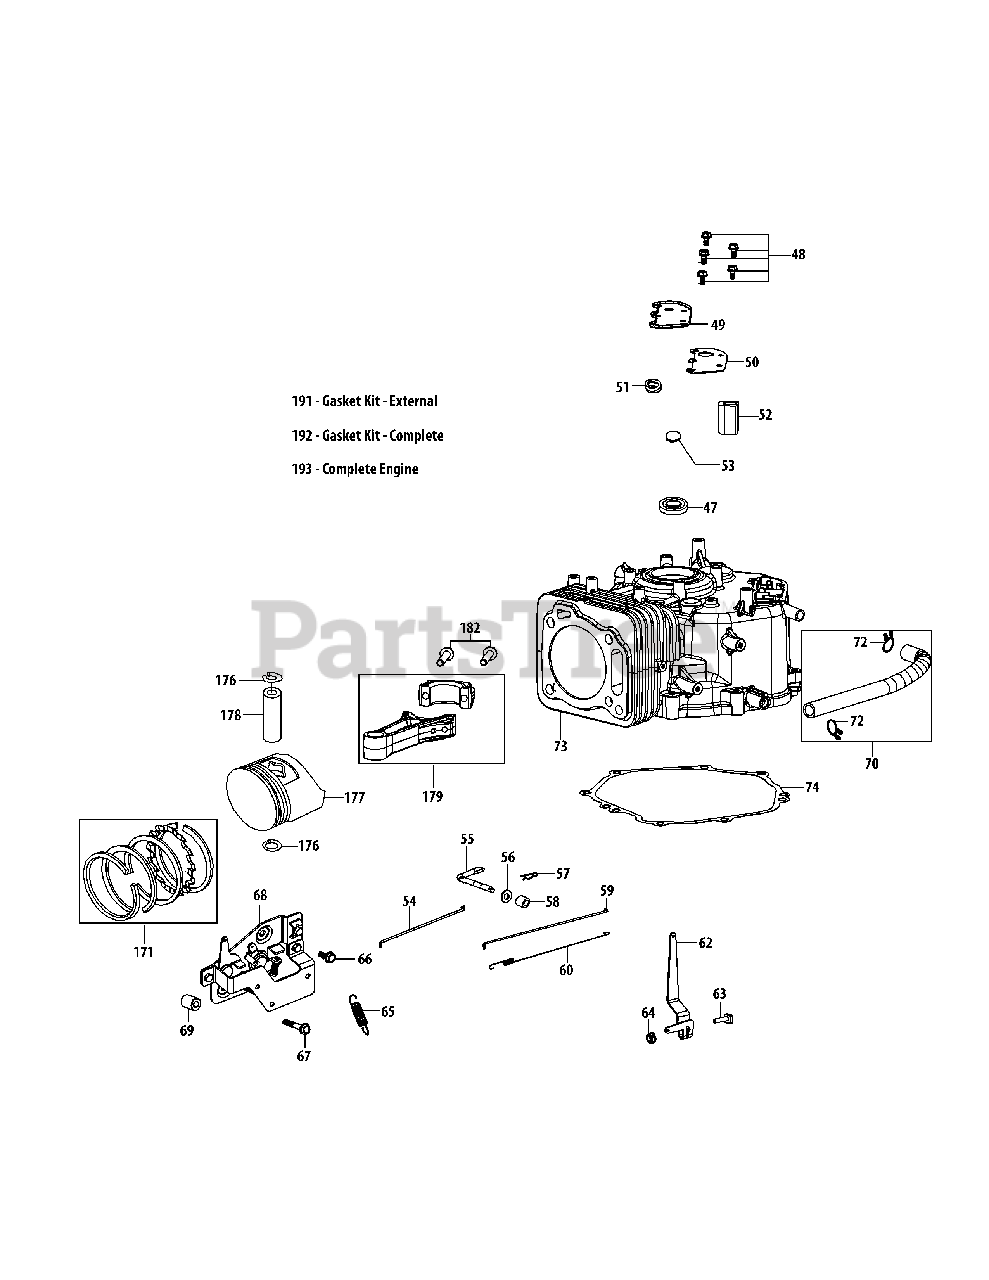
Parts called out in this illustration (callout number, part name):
47	Upper Crankshaft Seal
48	Bolt M6×14
49	Breather Cover Plate
50	Breather Gasket
51	Umbrella Valve
52	Mesh Screen
53	Umbrella Valve Set
54	Choke Linkage
55	Governor Arm Shaft/Improved
56	Governor Washer
57	Governor Cotter Pin
58	Governor Seal
59	Throttle Linkage
60	Throttle Linkage Spring
62	Governor Arm
63	Governor Arm Bolt
64	Governor Arm Nut M6
65	Governor Spring
66	Bolt M6×18
67	Bolt M6×38
68	Component Bracket/Separate
69	Component Bracket Spacer
70	Breather Hose Assembly
72	Breather Hose Clamp
73	Short Block Assembly
74	Crankcase Cover Gasket
171	Piston Ring Set
176	Piston Pin Snap Ring
178	Piston Pin
179	Connecting Rod Assembly
182	Connecting Rod Bolt
191	Gasket Kit - External
192	Gasket Kit - Complete
193	Complete Engine
